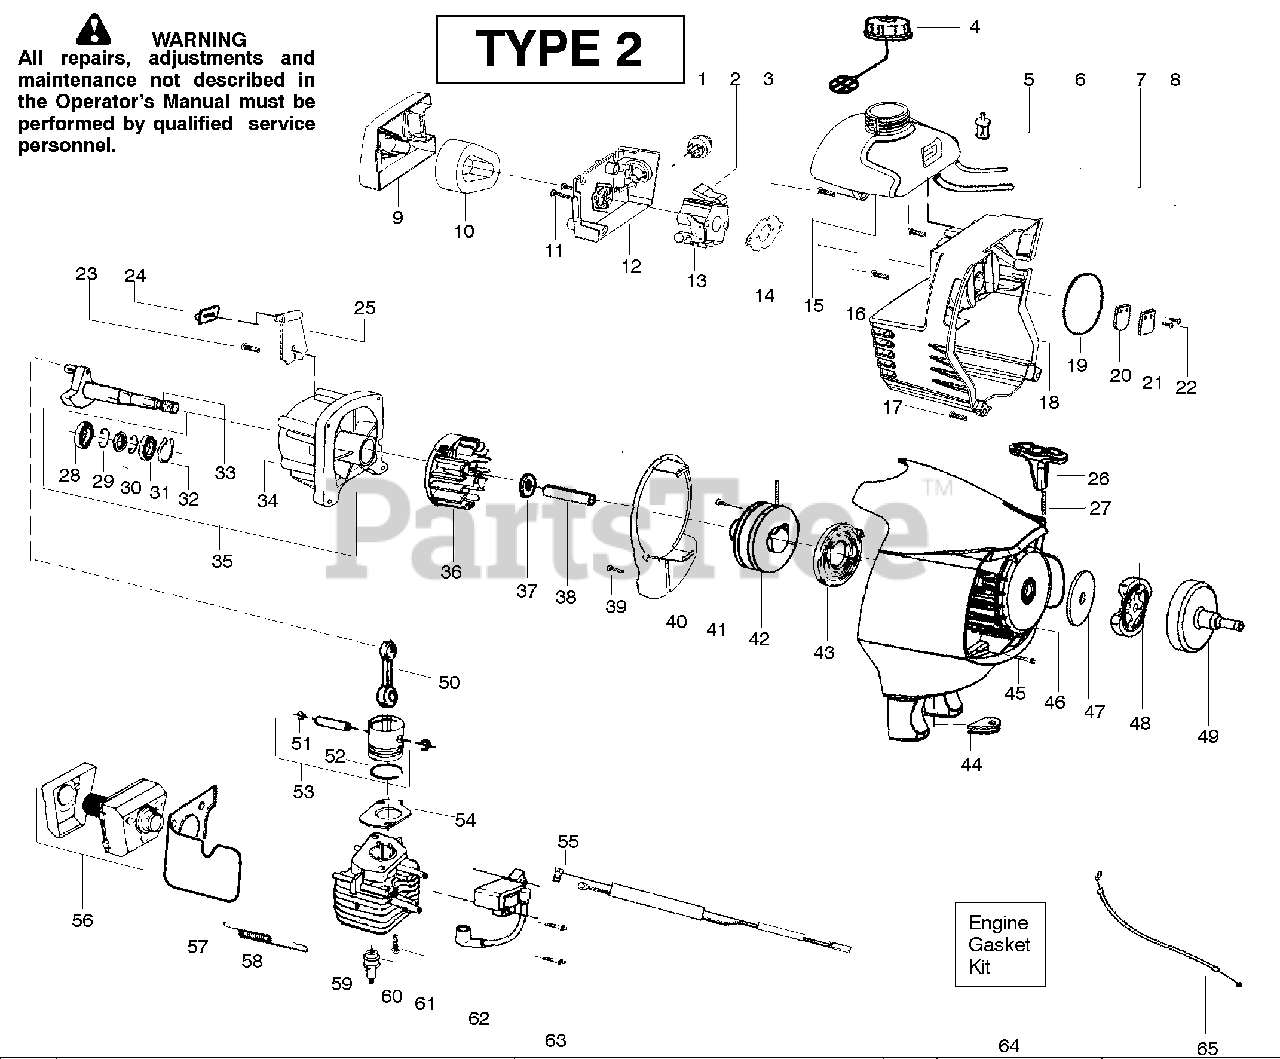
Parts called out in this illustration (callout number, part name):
2	Kit-Choke Lever
4	Cap-Fuel w/ret.
5	Assy-Fuel pickup
6	Kit-Fuel line
7	Kit-Fuel/Purge line
9	Cover-Air box
13	Assy-Carb(WT628)
14	Gasket-Carb.(kit)
15	Assy-Fuel Tank
16	Screw-Crankcase
19	O-ring-Shroud (kit)
22	Screw-Reed stop
23	Screw-Retainer
24	Isolator-Tank
26	Handle-Starter
27	Kit-Rope
28	Bearing-Inner
31	Bearing-Outer
32	Ret.-Crankshaft
33	Assy-Crankshaft
34	Assy-Crankcase
35	Assy-C'case/C'shaft
36	Assy-Flywheel
40	Plate-Baffle
42	Kit-Pulley
43	Spring-Starter
45	Screw-F/hsg.
46	Assy.-Fan Housing
47	Washer-Clutch
49	Drum-Clutch
50	Assy-Conn. Rod
51	Ret.-Piston pin
53	Kit-Piston
54	Gasket-Cylinder(kit)
55	Assy-Leadwire
58	Spring-Muffler
60	Plug-Spark(RCJ-6Y)
61	Bolt-Cyl. 1/4-20"
62	Module-Ignition
64	Kit-Gasket
65	Assy-Throttle cable
